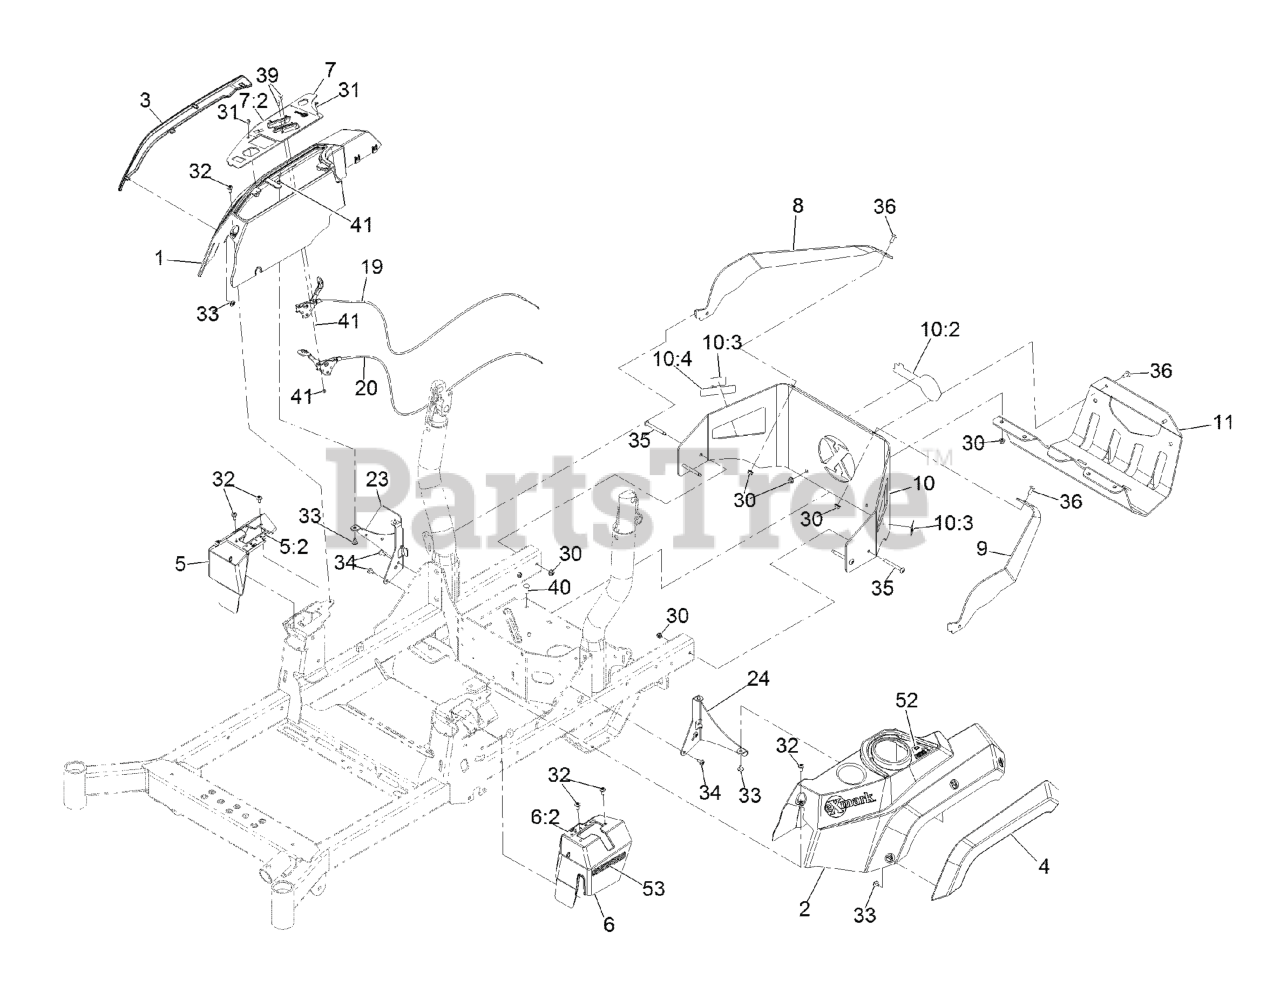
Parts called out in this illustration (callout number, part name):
1	CONSOLE-EXMARK, RH
2	CONSOLE, LH
3	FENDER-RH
4	FENDER-LH
5	COVER-CONTROL, MOTION (RH
5:2	Decal-Control, Motion (RH)
6	COVER-CONTROL, MOTION (LH
6:2	Decal-Control, Motion (LH)
7	CTRL PANEL ASM W/DECAL
7:2	DECAL-CONTROL PANEL
8	SUPPORT-UPPER, RH
9	SUPPORT-UPPER, LH
10	REAR GUARD ASM
10:2	DECAL, EXMARK LOGO
10:3	DECAL-WARNING
10:4	DECAL-ARRESTOR, SPARK
11	GUARD-MUFFLER
19	CABLE-CONTROL, CHOKE
20	CABLE-CONTROL, THROTTLE
23	SUPPORT-CONSOLE, RH
24	BRACKET-CONSOLE, LH
30	NUT-HF, NI
31	SCREW-HWH
32	SCREW-SHOULDER
33	SCREW-TORX
34	SCREW-TORX
35	SCREW-TORX
36	SCREW-TORX
39	BOLT-CARR
40	SCREW-CARR
41	NUT-LOCK, NI
52	DECAL-FILL, FUEL
53	DECAL-S-SERIES
